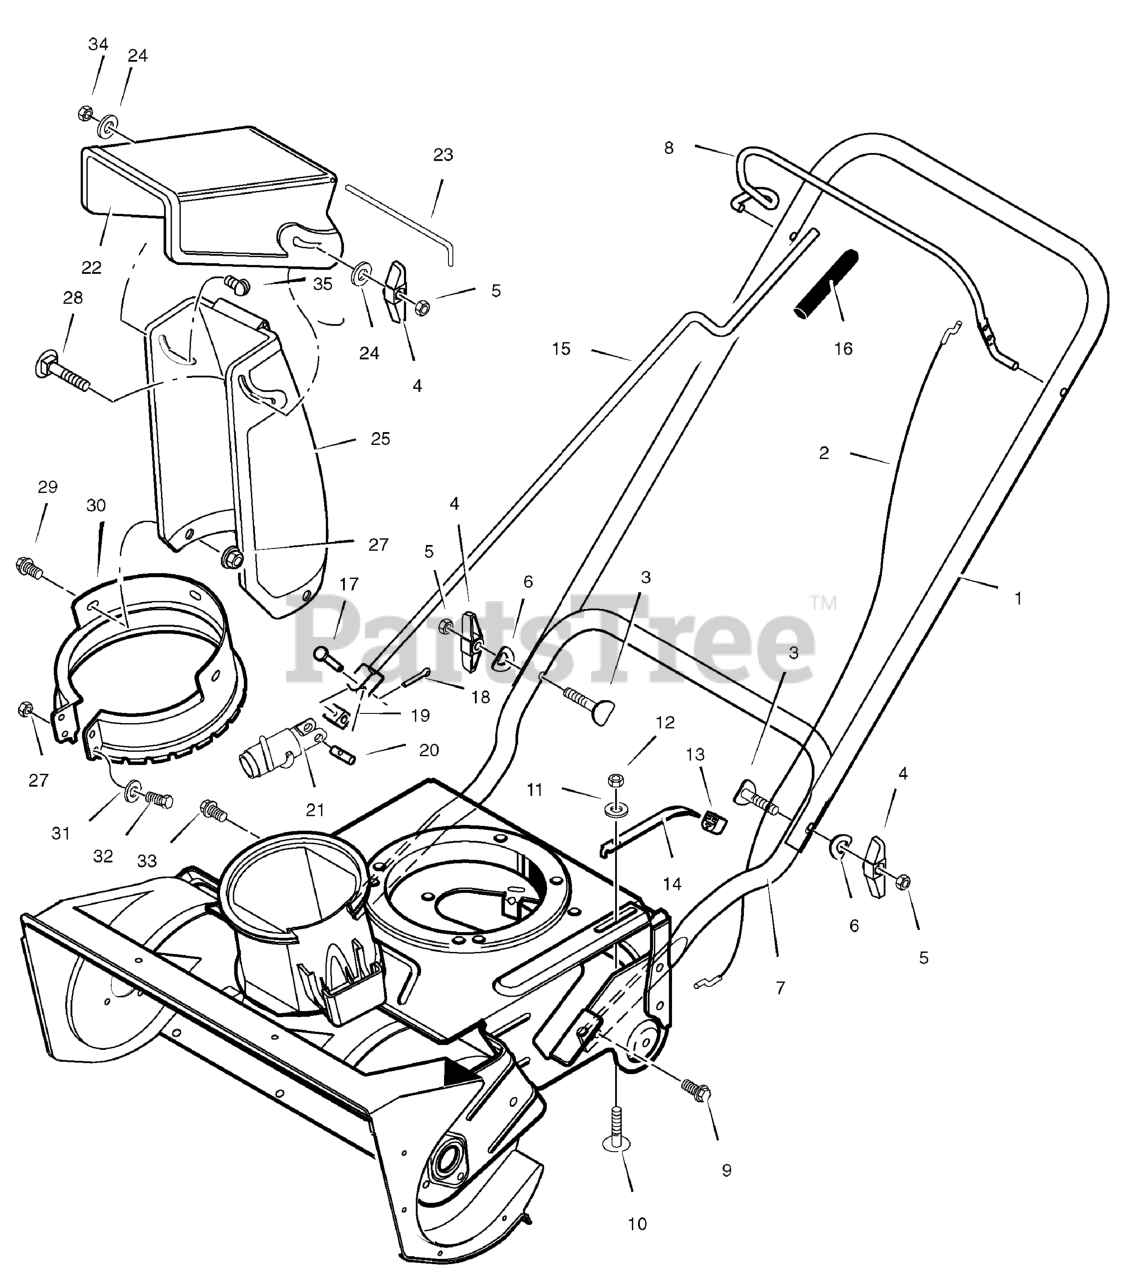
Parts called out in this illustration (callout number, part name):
1	Handle, Upper
2	Cable, Auger Drive
4	Knob
5	Nut
7	Handle, Lower
8	Lever, Auger Drive
9	Screw
13	Bushing, Tensioner
14	Bracket, Cable Tensioner
15	Rod, Crank
16	Grip, Crank Rod
17	Pin, Clevis
18	Pin, Cotter
19	Block, Universal Pivot
21	Gear, Worm
22	Deflector
23	Pin, Pivot
24	Washer
25	Chute, Discharge
30	Ring, Chute
31	Washer
33	Bolt
34	Locknut
